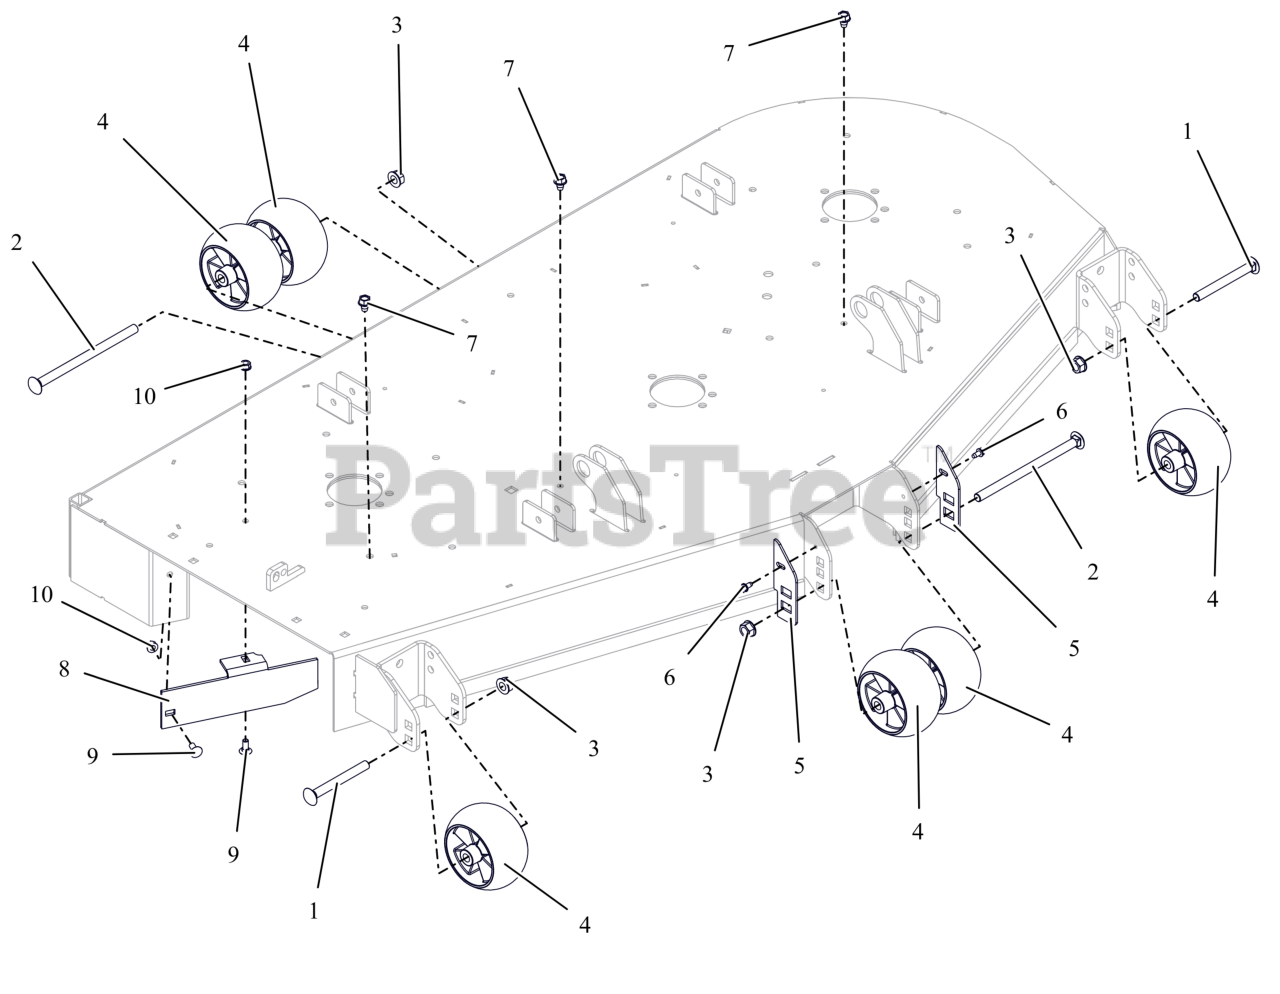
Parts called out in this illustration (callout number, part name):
1	BLT-RHNS .50-13X4.50 G5 ZCC NS
2	BLT-RHSN .50-13X8.00 G5 ZCC NS
3	NUT-LK-CTR-FLG .500-13 GG ZCC
4	WHEEL, ANTI SCALP - 5X3 CTR W/RIBS
5	PLATE, ANTI SCALP WHEEL 60" (ORANGE)
6	SCR-TAP .25-20X.50 HWH ZCC
7	SCR,TAP .375-16X.50 HWH TR ZCC
8	BAFFLE, 60" DISCHARGE
9	BLT,RHSN .31-18X.75 G5 ZCC
10	NUT,LK-CTR-FLG .31-18 GF ZCC
